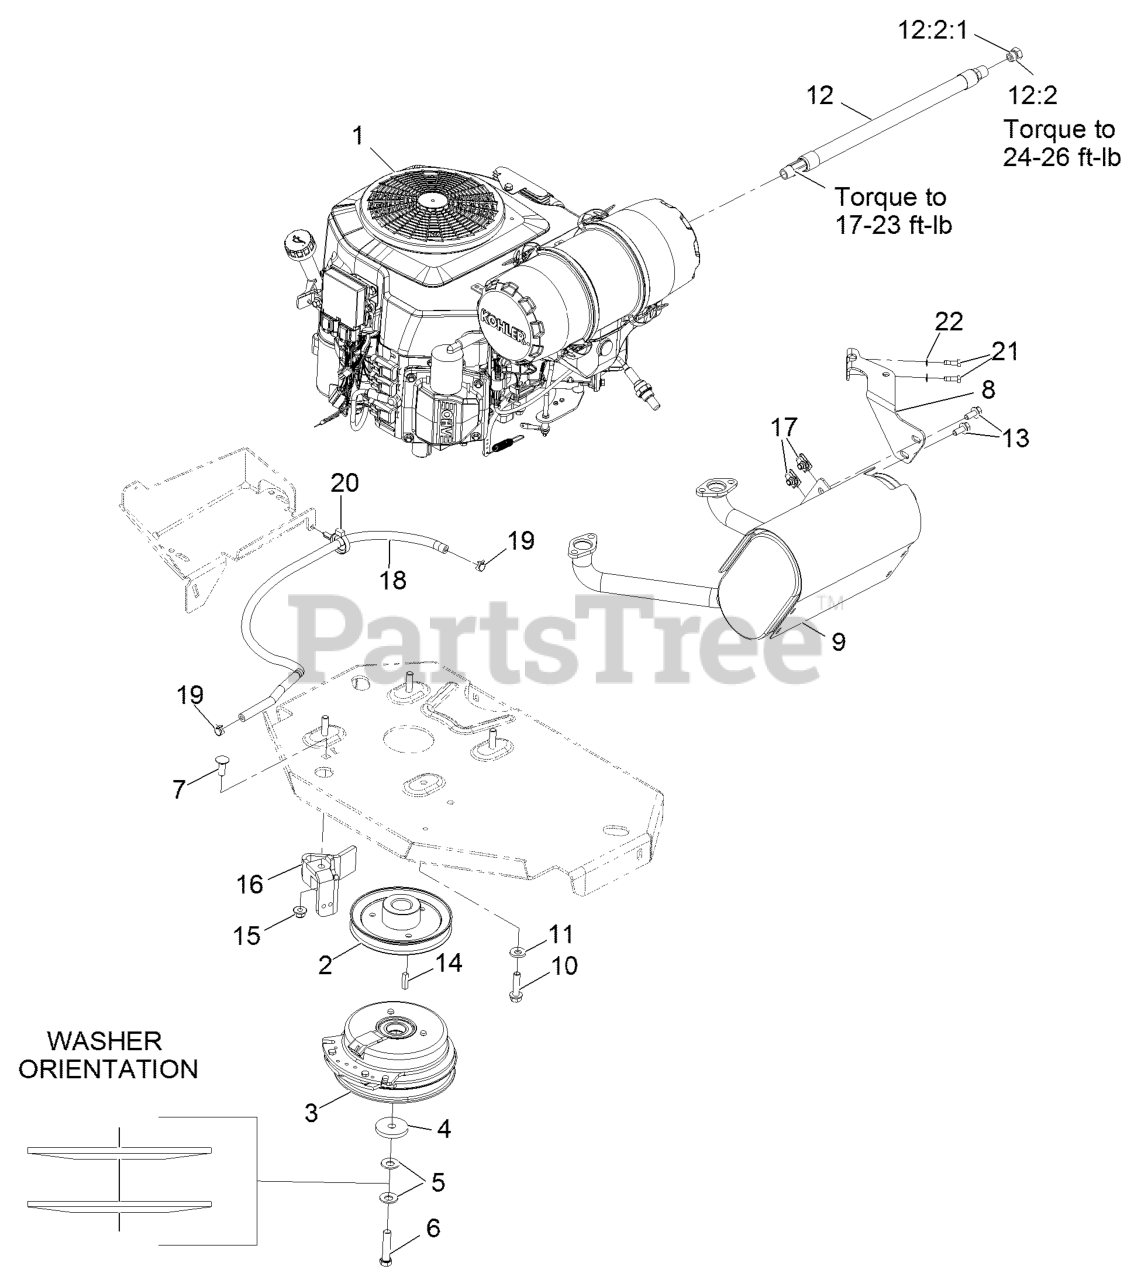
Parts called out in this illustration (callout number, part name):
1	Engine-Kohler
2	SHEAVE
3	CLUTCH KIT
4	WASHER-CLUTCH
5	WASHER-SPRING
6	SCREW-HH 7/16-20 X 1 1/2 W/LOCTITE
7	SCREW-CARR
8	MUFFLER BRACKET KIT
10	SCREW-HWH
11	WASHER-BELLEVILLE
12	OIL DRAIN HOSE ASM
12:2	PLUG-HH
12:2:1	O-RING
13	SCREW-HHF
15	NUT-HF, NI
16	CLUTCH-ANCHOR
18	HOSE-FUEL
19	CLAMP-HOSE
20	CLAMP-HOSE
21	SCREW-HH M6-1 X 20Mm W/Patch
22	WASHER-SPRING
